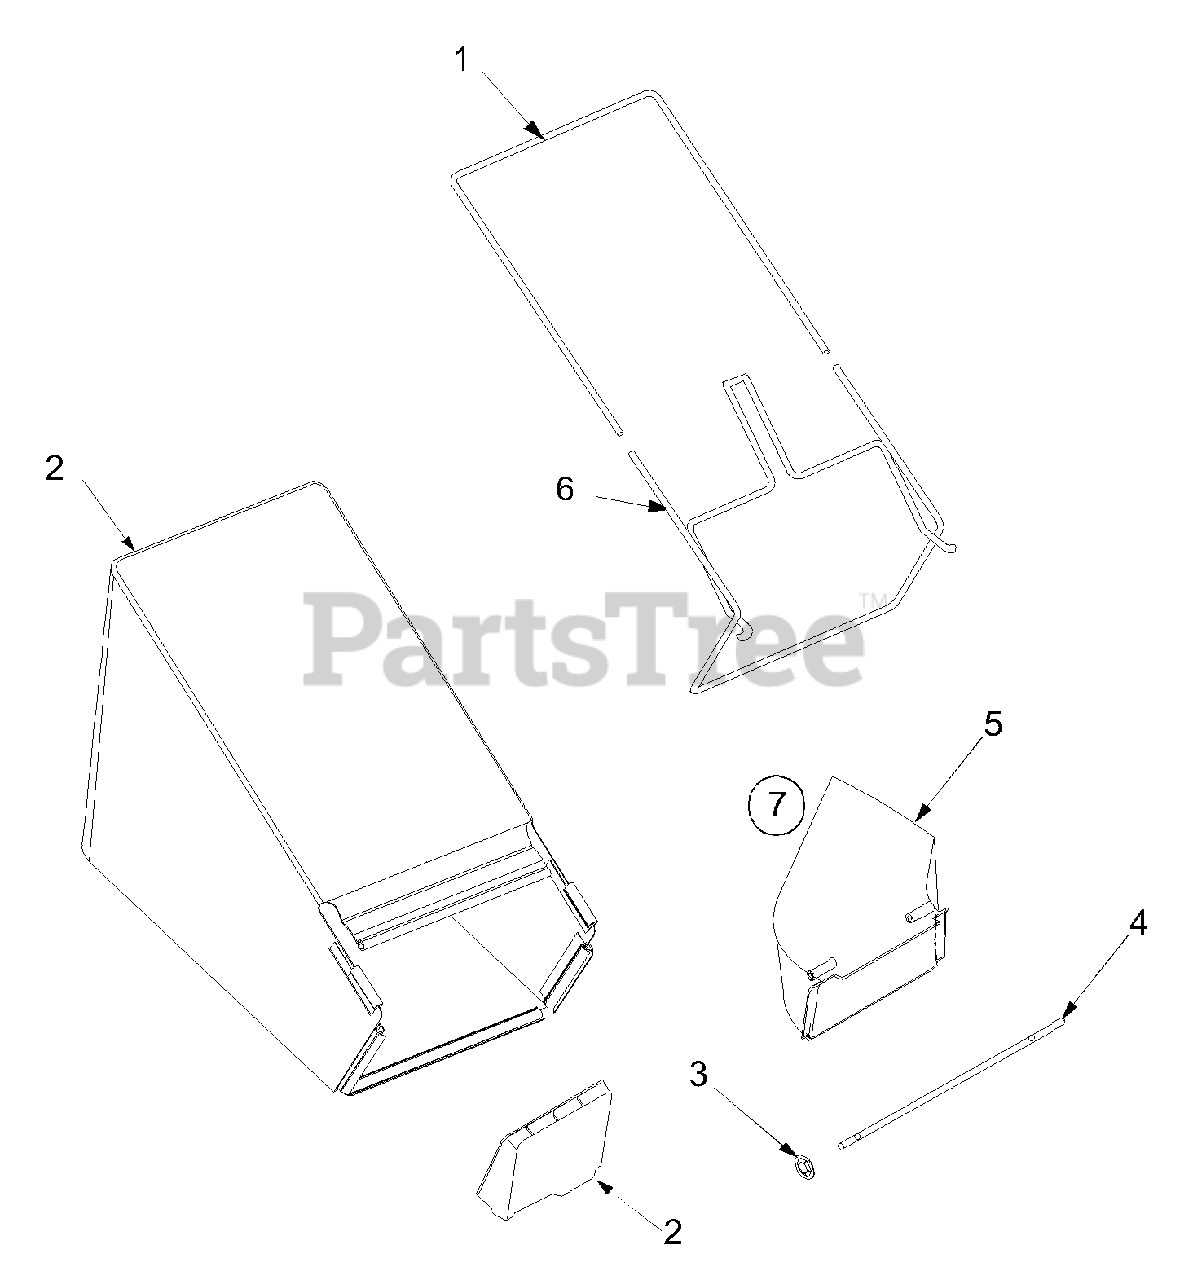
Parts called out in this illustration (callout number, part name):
2	Mulcher Plug
3	Nut: Spd. .3125 ID
5	Side Discharge Adapter
